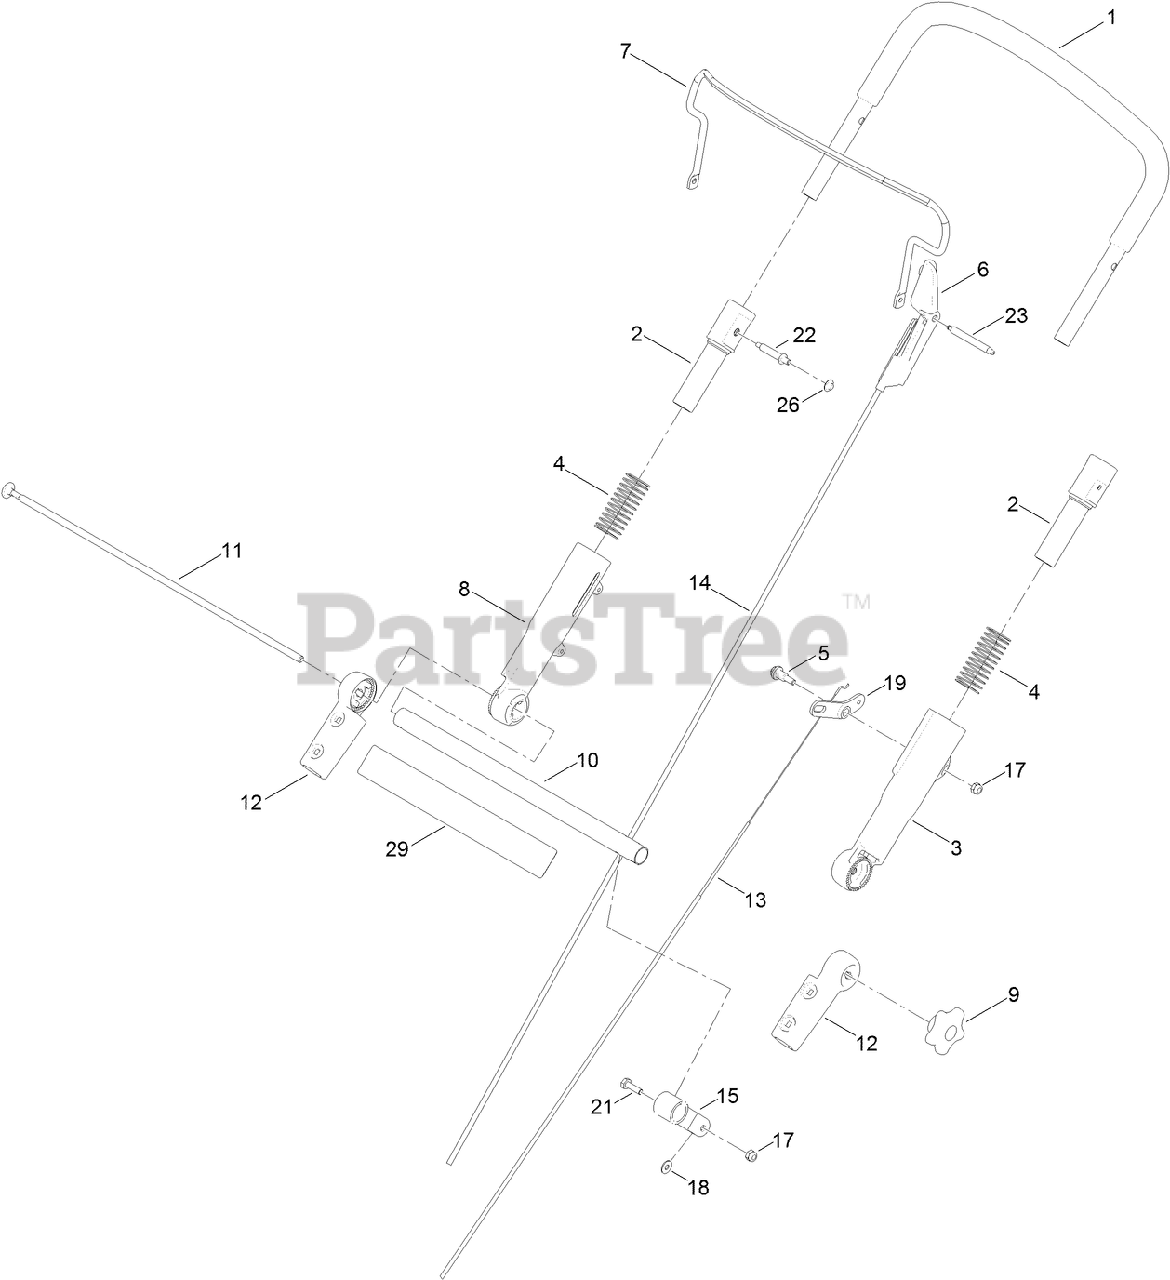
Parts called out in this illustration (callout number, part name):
1	UPPER HANDLE ASM
2	SLEEVE-INNER
3	SLEEVE-OUTER, LH
4	SPRING-COMPRESSION
5	BOLT-SHOULDER
6	STOP-PIVOT
7	BAIL-BRAKE
8	SLEEVE-OUTER, RH
9	KNOB-HANDLE
10	TUBE-CROSS
11	ROD-THREADED
12	MOUNT-HANDLE, LOWER
13	CABLE-TRACTION
14	CABLE-BRAKE
15	CLAMP-CABLE
17	NUT-LOCK, NI
18	WASHER-FLAT
19	LEVER-TRACTION
21	SCREW-HH
22	PIN-HANDLE
23	PIN-BAIL, LH
26	RETAINER-PUSH ON
29	DECAL-ADS
